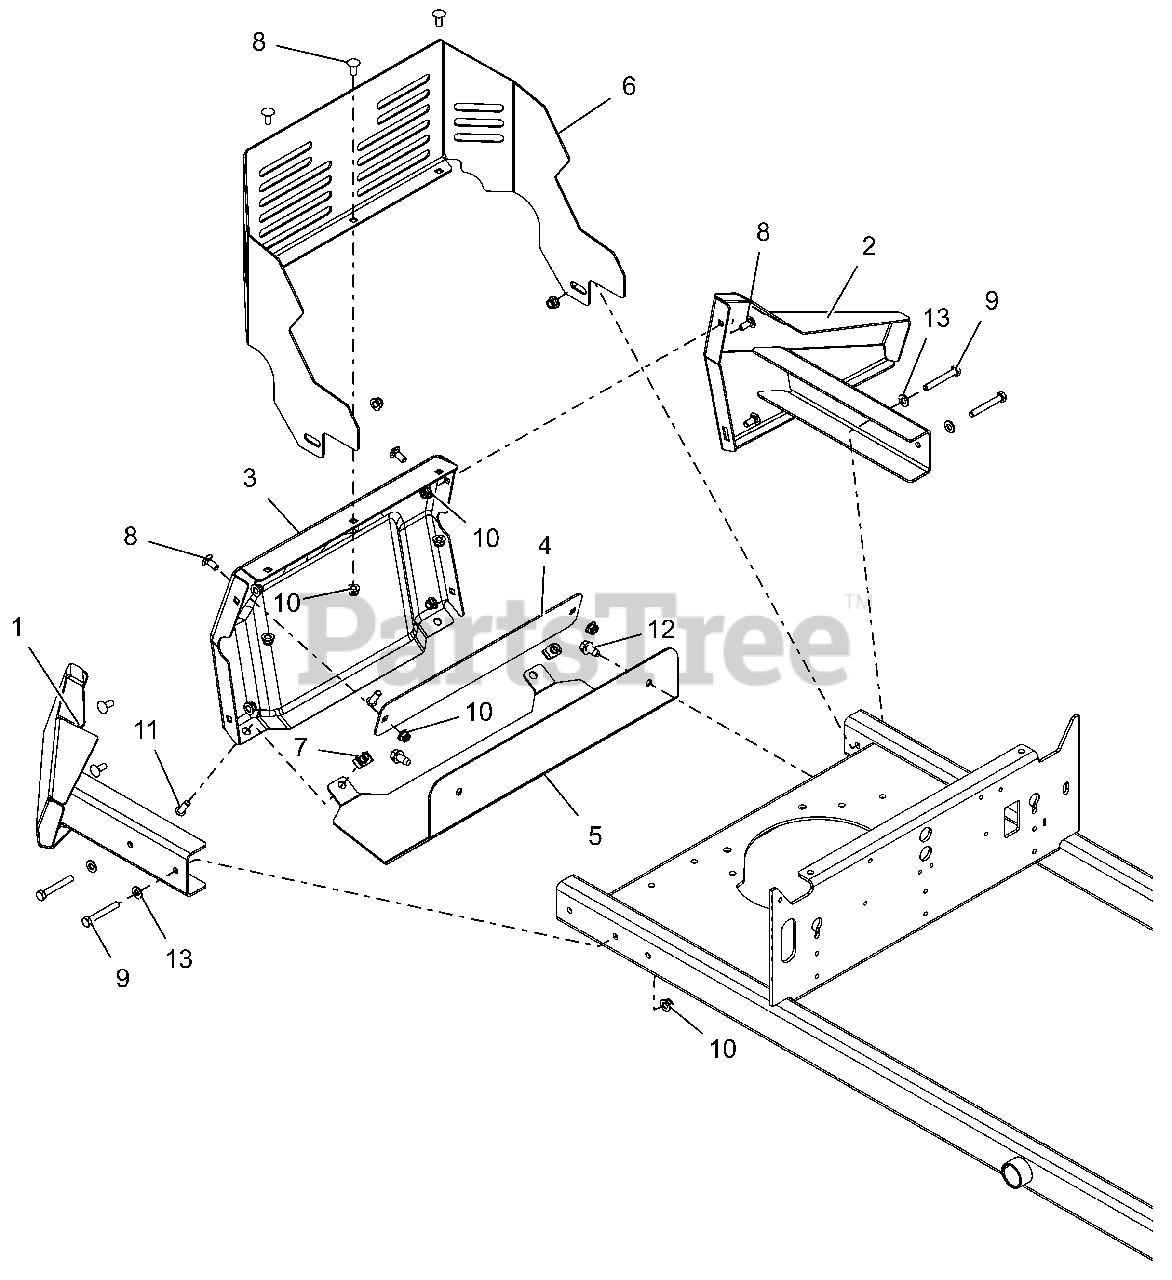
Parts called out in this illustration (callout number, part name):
1	RH RR BMPR WING W/SAFETY DECAL
2	LH RR BMPR WING W/SAFETY DECAL
3	PT200/400 REAR BUMPER - BLACK
4	BACKER PLATE - RED
5	PT100 MUFFLER GUARD -BLACK
6	GUARD, PT ENGINE
7	NUT-CLIP RETAINER 5/16-18X.56
8	@BLT-RDHDSQNK .31-18X.75 G5YZ
9	@BLT-HEX .31-18X2.25 GR5 YWZC
10	@NUT-LK-NYL-FLG .31-18 YWZC
11	SCR-SKH .31-18X1.0 BTNHD YWZC
12	@SCR-TAP .38-16X.75 HWH TR YWZ
13	@WSHR-FL-STL.344X.688X.065YWZC
